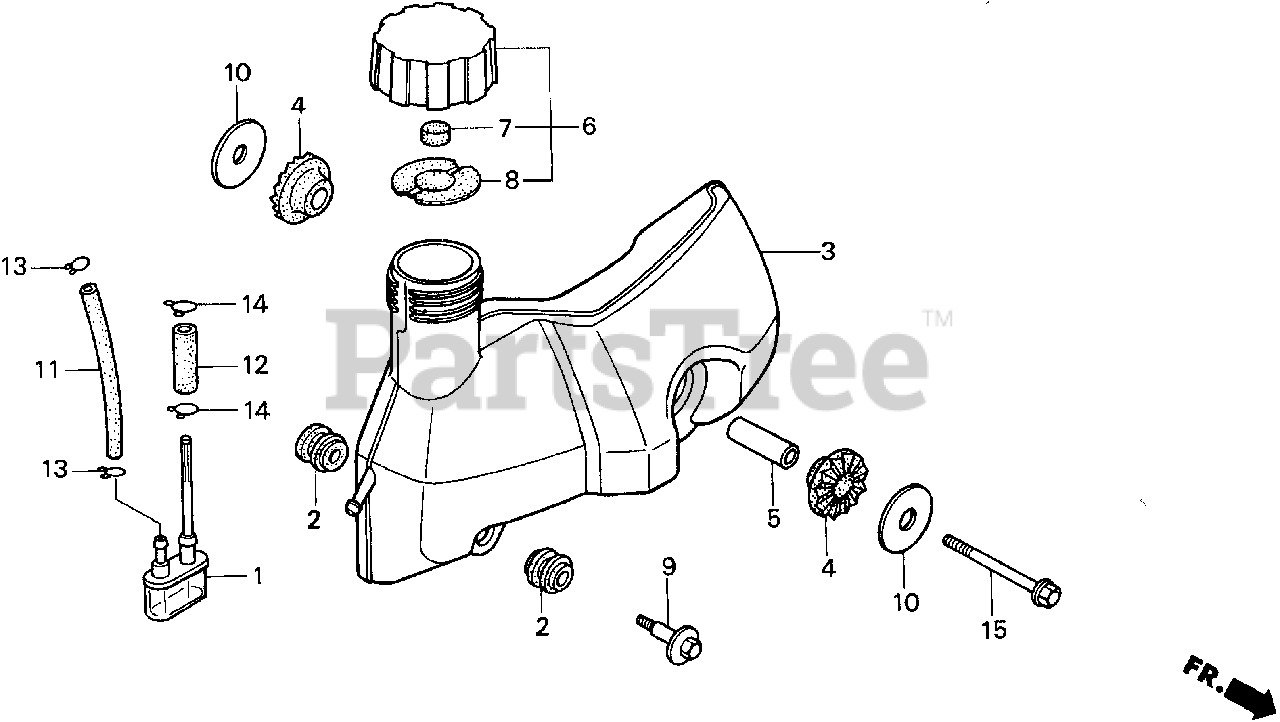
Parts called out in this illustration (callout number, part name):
1	FILTER, FUEL
2	RUBBER, TANK SETTING
3	TANK, FUEL
4	RUBBER B, TANK MOUNTING
5	COLLAR, TANK SETTING
6	CAP ASSY., FUEL TANK
7	SPONGE, FUEL CAP BREATHER
8	GASKET, FUEL CAP
9	BOLT, TANK SETTING
10	WASHER, TANK MOUNTING
11	BULK HOSE, FUEL (4.5X3000) (Honda Code 5137104). (4.5X140)
12	BULK HOSE, FUEL (7.5X8000) (7.3X160)
13	CLIP, TUBE (B8)
14	CLIP, TUBE (B12) Use from Engine SN 2086984.
15	BOLT, FLANGE (8X50)
